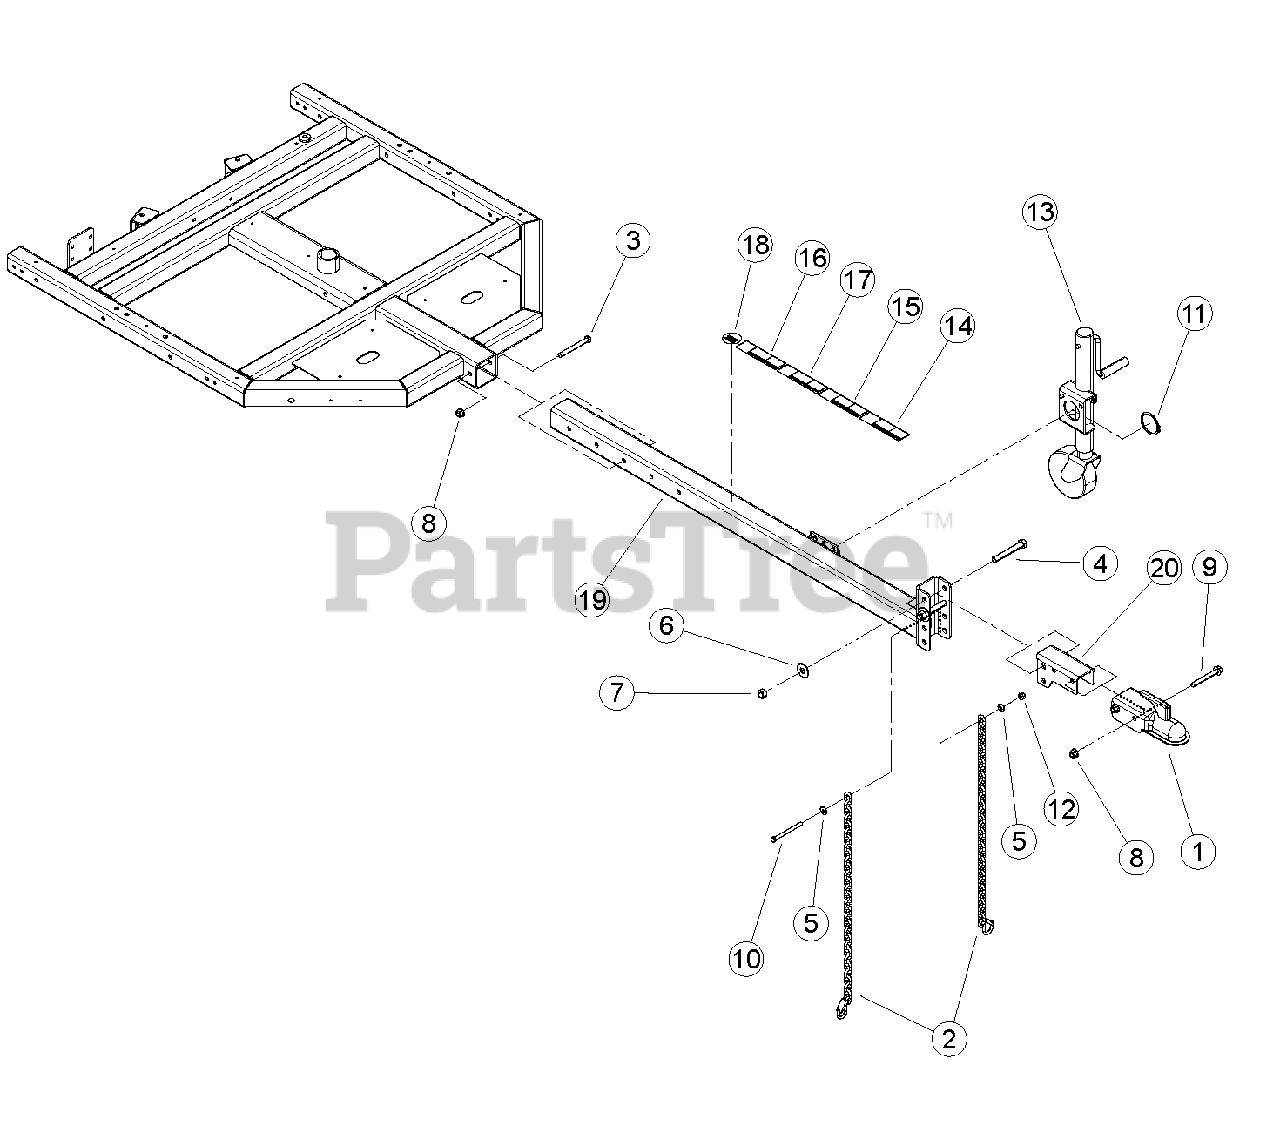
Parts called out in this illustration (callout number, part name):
1	COUPLER, 2 IN
2	CHAIN, SAFETY 5,000 LB W/ LATCH
3	BOLT, 1/2 X 4-1/2" GR5 HHCS NC ZP
4	BOLT, 5/8 X 4-1/2 HEX HD G5 ZP
5	WASHER, 3/8" FLAT ZP
6	WASHER, 5/8" FLAT ZP
7	NUT, 5/8" CENTERLOCK ZP GR5
8	NUT, 1/2-13 NYLOCK FLANGE
9	BOLT, 1/2-13 X 4 HWH GR5 CZP
10	BOLT, 3/8 X 4-1/2" HHCS GR5 NC ZP
11	SNAP RING, 2-1/2 EXTERNAL
12	NUT, 3/8-16 NYLOCK FLANGE
13	JACK, PIVOTING W SWIVEL CASTOR
14	DECAL, SAFETY CHAINS
15	DECAL, TRAILER ELECTRICAL
16	DECAL, CHECK WHEELS
17	DECAL, SAFE COUPLING
18	DECAL, NATM COMPLIANCE
19	WELDMENT, HITCH POLE W/ PLATE
20	MOUNT, COUPLER
